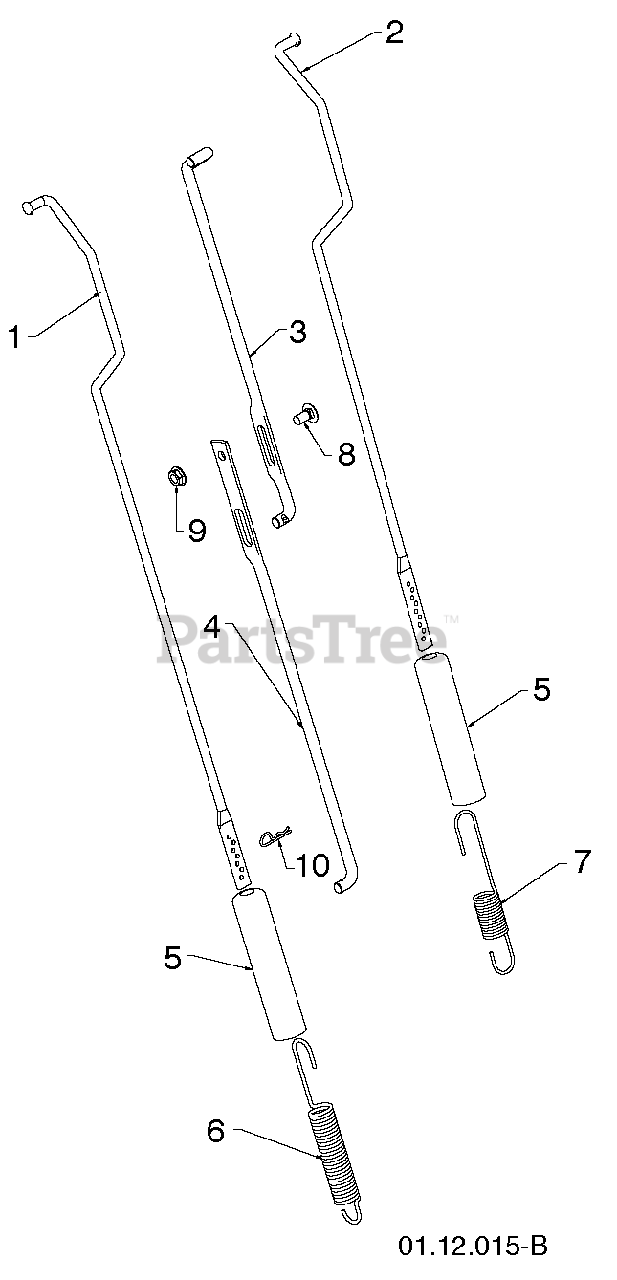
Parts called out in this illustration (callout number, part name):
1	ROD.IMPELLER.CONTROL.HYD I.13
2	ROD.TRACTION
3	ROD.SHIFTER.TOP.HYD.SNOW
4	ROD, LOWER, SPEED CONTROL
5	SLEEVE, SPRING
6	SPRING.CONTROL.ROD.SNOW
7	SPRING.TRACTION.ROD.SNOW
8	BOLT
9	NUT.FLANGE.5/16
10	SPRING RETAINER
